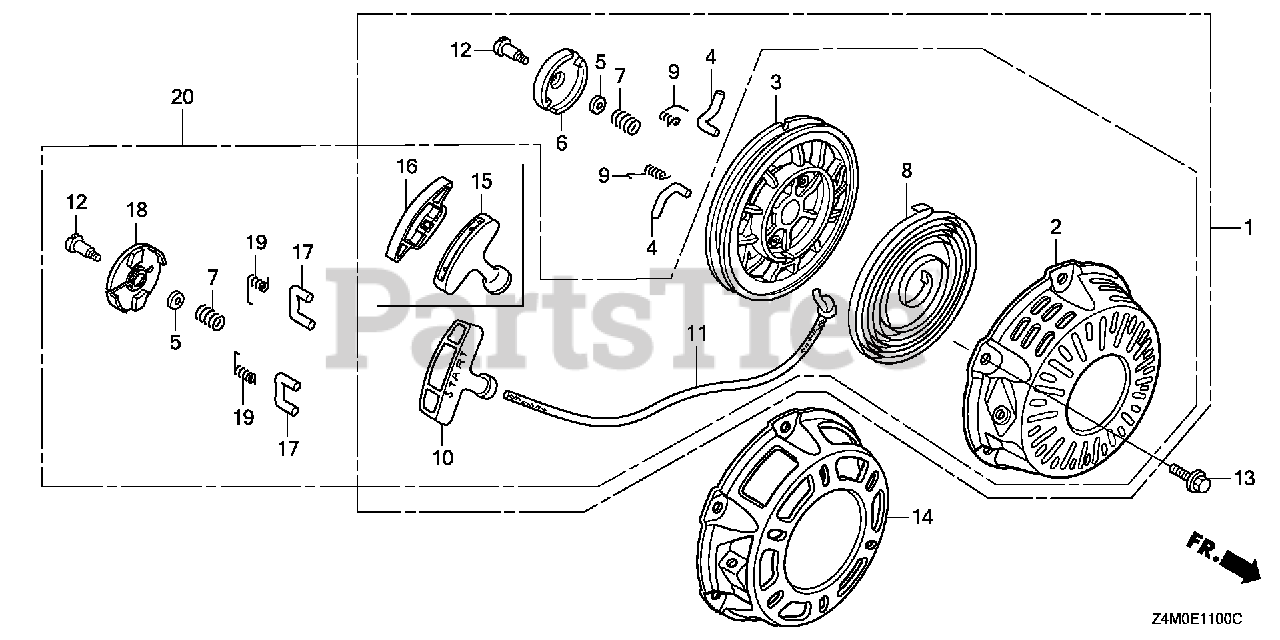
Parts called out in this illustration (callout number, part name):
1	STARTER ASSY., RECOIL *NH1* (BLACK)
1	STARTER ASSY., RECOIL *R280* (POWER RED)
2	CASE, RECOIL STARTER *R280* (Honda Code 7346836). (POWER RED)
2	CASE, RECOIL STARTER *NH1* (Honda Code 4193058). (BLACK)
3	REEL, RECOIL STARTER
3	REEL, RECOIL STARTER (BLACK)
4	RATCHET, STARTER
5	PLATE, FRICTION
6	GUIDE, RATCHET
7	SPRING, FRICTION
8	SPRING, RECOIL STARTER
9	SPRING, RETURN
10	KNOB, RECOIL STARTER
10	GRIP, STARTER
11	ROPE, RECOIL STARTER (#5X55")
12	SCREW, SETTING
13	BOLT, FLANGE (6X10)
